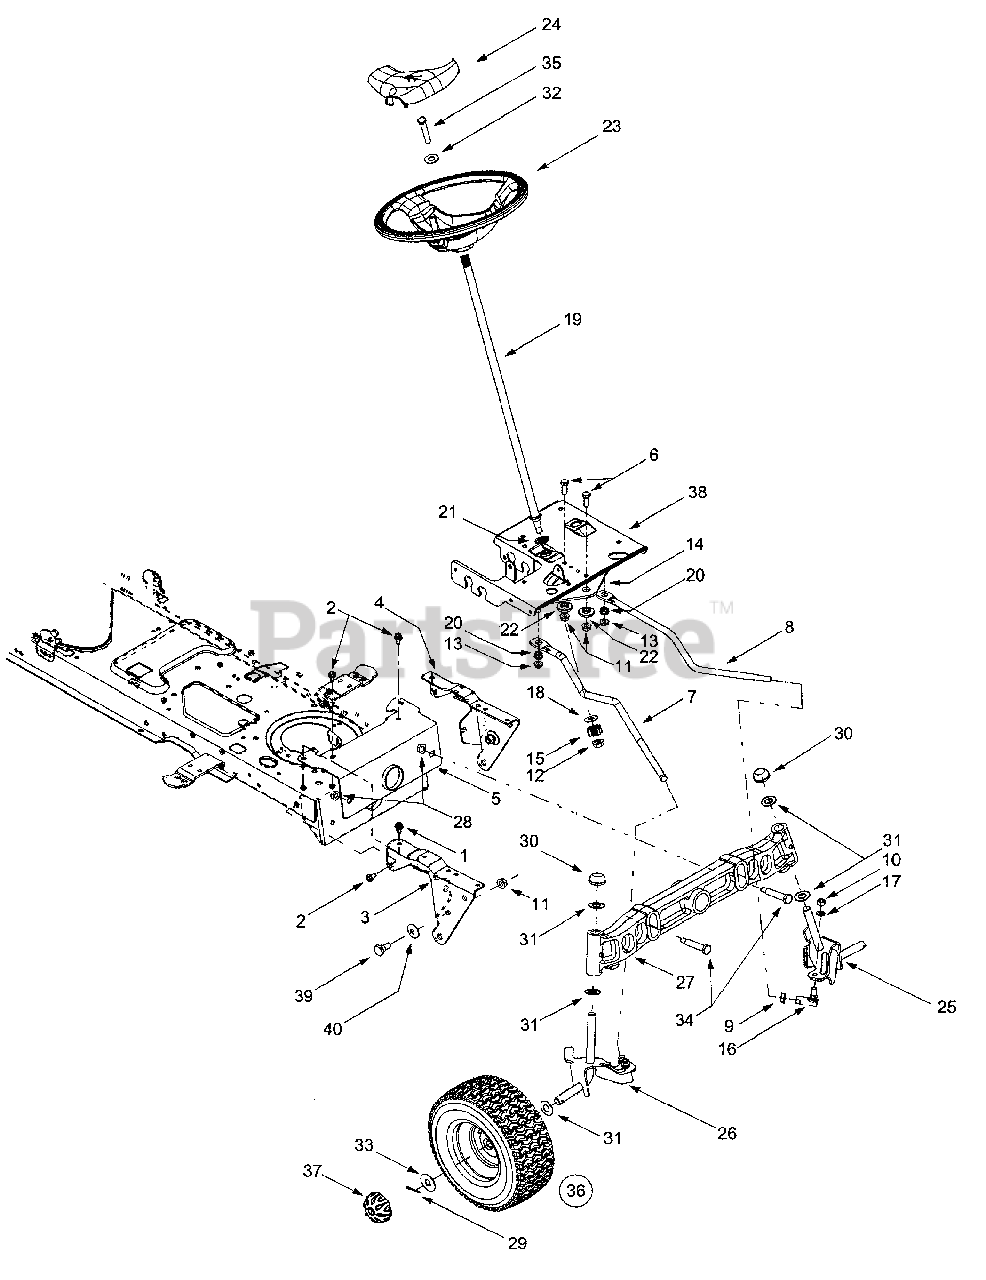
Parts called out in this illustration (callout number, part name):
1	Self-tapping Screw, 5/16-18 x .75
2	Self-tapping Screw, 16-18 x .625
6	Hex Cap Screw, 3/8-16 x 1 (Grade 5)
7	RH Drag Link
8	LH Drag Link
9	Jam Nut, 7/16-20 (Grade 2)
10	Hex Nut, 3/8-24 (Grade 2)
11	Flange Lock Nut, 3/8-16
12	Flange Lock Nut, 7/16-20
13	Flange Lock Nut, 5/16-18
14	Steering Gear, 11/90 Ratio
15	Steering Pinion Gear
16	Ball Joint, 7/16-20
17	Lock Washer, 3/8
18	Flat Washer, .51 x 1.12 x .06
19	Steering Shaft, .625 OD x 24.4
20	Plastic Bushing, .38 ID
21	Hex Flange Bearing, 5/8
22	Shoulder Spacer, .38 ID
23	Soft Touch Steering Wheel
24	Steering Wheel Cap
25	LH Axle Assembly, .75 Diameter
26	RH Axle Assembly, .75 Diameter
27	Cast Iron Pivot Bar w/ Fittings, .750
28	Flange Lock Nut, 3/8-16
29	Cotter Pin
30	Push Cap, .75
31	Flat Washer, .78 x 1.59 x .06
32	Bell Washer, .34 x .872
33	Flat Washer, .635 x 1.589 x .06
34	Shoulder Screw, .5 x 2.2, 3/8-16
35	Hex Bolt, 5/16-18 X 1
36	Wheel Assembly Complete, 16 x 6.
36	Tire Only, Square Shoulder
37	Hub Cap
39	Shoulder Screw, 3/8-16
40	Bell Washer, .39 x 1.13 x .062
